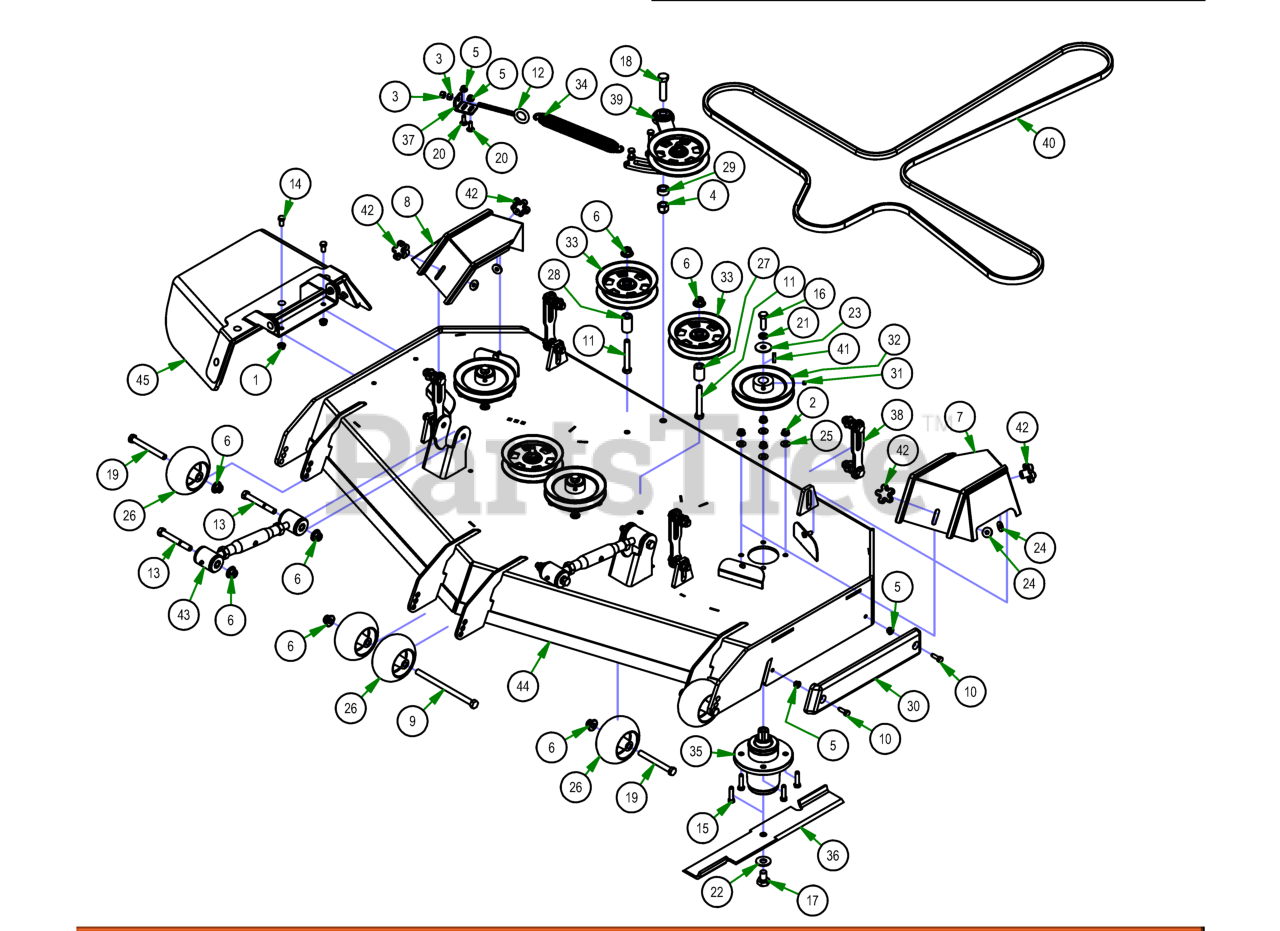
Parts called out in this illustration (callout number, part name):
1	3/8" Flange Nut
2	3/8-16 NYLON INSERT FLANGE LOCKNUT (GR.F) ZINC
3	3/8" Hex Nut
4	5/8 Std NC Nylock Nut
5	5/16" Nylon Flange Nut
6	1/2-13 NYLON INSERT FLANGE LOCKNUT ZINC
7	2019 61" Outlaw Gen2 Pulley Cover Left
8	2019 61" Outlaw Gen2 Pulley Cover Right
9	1/2-13 x 8 Hex Bolt Grade 5
10	5/16-18 x 1 GR 5 Hex Bolt Zinc
11	1/2 x 3 1/2 Flange Bolt Grade 8
12	4" 3/8-16 Eye Bolt
13	1/2" x 4" Bolt (Grade 8)
14	3/8" x 3/4" Hex Bolt
15	3/8-16 X 1-1/2 HEX CAP SCREW (GR.5) ZINC
16	1/2"-20 x 1 1/2 - Grade 5 Fine Thread Bolt
17	5/8" x 1 1/2" Grade 8 Hex Bolt (Fine)
18	5/8" x 2 1/2" Grade 5 Hex Bolt (Coarse)
19	1/2" x 4 1/2" Bolt
20	5/16" x 7/8" Carriage Bolt
21	1/2" Lock Washer
22	5/8'' Flat Washer
23	1/2" Belleville Washer
24	.360 ID Plastic Washer-Black
25	5/16 USS FLAT WASHER (7/8 OD) ZINC
26	2019 Deck Wheel
27	.502 ID X .750 OD X 1.500 Long Spacer
28	1 3/4" Pulley Spacer
29	5/8" x 1/" Collar W/One Set Screw
30	REVISED TRIM BUMPER_20180226
31	5/16 Set Screw
32	6 1/4" Drive Pulley
33	5-3/4 Idler Pulley
34	2019 Outlaw Gen2 Deck Spring
35	OUTLAW SPINDLE ASSEMBLY
36	61 inch Fusion Blade
37	2019 Deck Eye Bolt Tab
38	Deck Hangar Assembly
39	2019 Rebel Rogue Deck Idler
41	1/4" x 1" Key
42	5/16" Knob
43	Turnbuckle
44	2019 Sloped 61" Deck
45	2019 Outlaw Gen2 Chute Assembly
